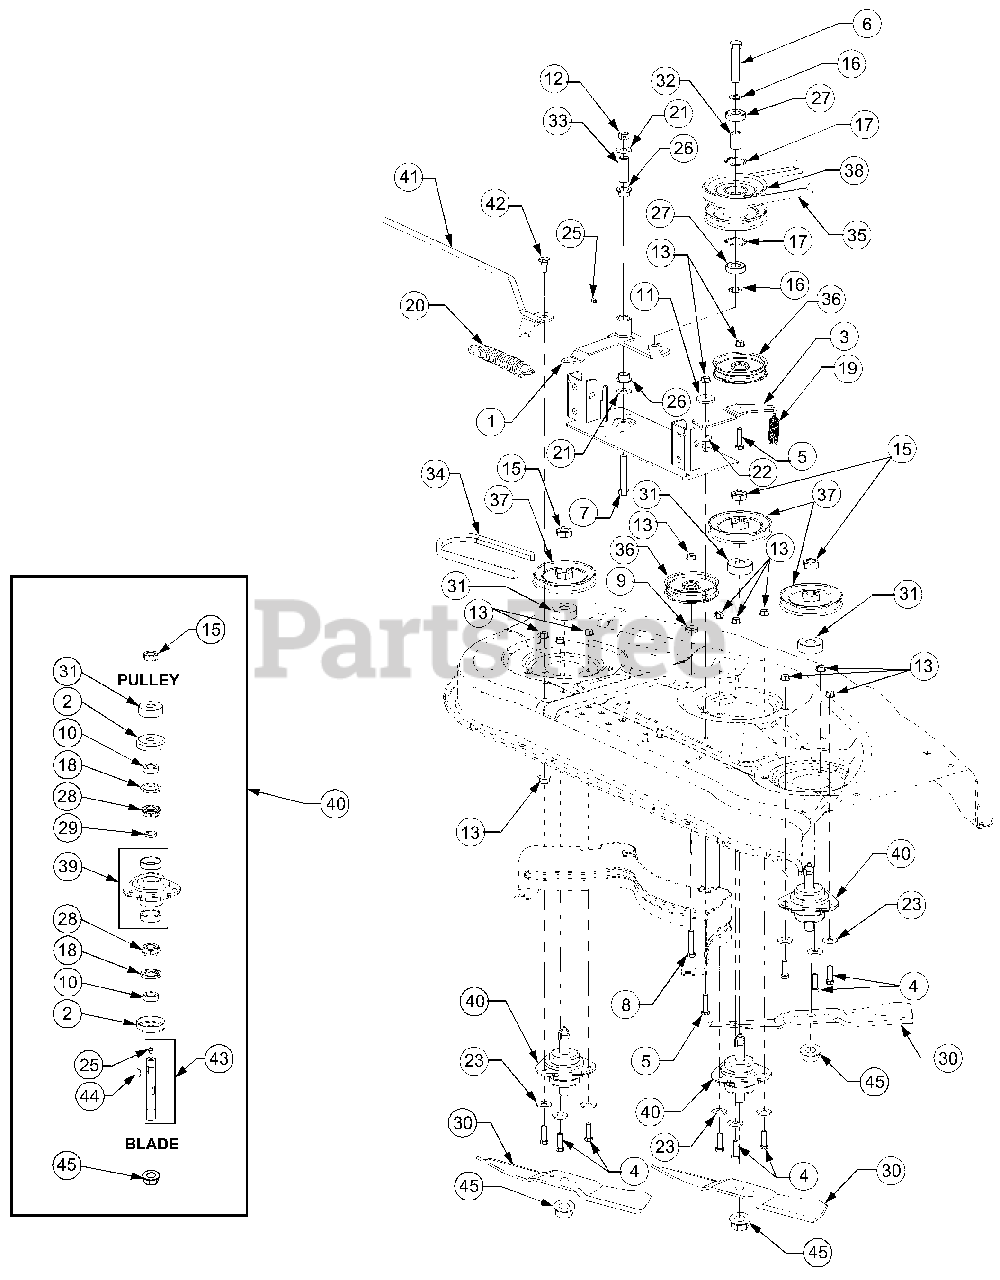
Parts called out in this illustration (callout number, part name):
1	Pivot Arm, Double Pulley
2	Cup, Spindle
4	Screw, Hex Cap 3/8-16 x 1.25 GR5
5	Screw, Hex Cap, 3/8-16 x 1.5 GR5
6	Screw, Hex Cap, 5/8-18 x 3 GR5
7	Screw, Hex Cap, 1/2-20 x 3 GR8
8	Screw, Hex Cap, 3/8-16 x 2
9	Spacer, .380 ID x 1 OD x .32
10	Spacer, .755 ID x 1.25 OD x .44
11	Spacer, Shoulder
12	Nut, Hex Center Lock, 1/2-20
13	Nut, Hex Flanged Lock, 3/8-16
15	Nut, Hex Jam, 3/4-16 GR5
16	Washer, Flat, .65 x 1.25 x .075
17	Snap Ring, Internal
18	Seal, Oil, 1.25 x 1.874 x .25
19	Spring, Extension, .75 OD x 6.12
20	Spring, Extension, 1.25 OD x 8.15
21	Washer, Flat, .531 x 1.25 x .1 Thk
22	Washer, Flat, .385 x 1 x .127 Thk
23	Washer, Flat, .406 x 1.0 x .105
25	Fitting, 3/16 Drive Lube
26	Bearing, Flange, 3/4 ID x .53
27	Bearing, Ball, .62 x 1.57 x .470
28	Cone, Bearing
29	Spacer, Bearing
30	Blade, Low Lift, 16.5"
31	Spacer
32	Spacer, Pulley, .635 ID x .88 OD x
33	Spacer, Idlr Brkt, .51 ID x .75 OD x
34	Belt, Spindle, A-Section x 105"
35	Belt, PTO, B-Section x 111.2"
36	Pulley, Flat Idler, 4.06 OD
37	V-Pulley, 4.70 OD
38	Pulley, Double
39	Housing w/Cups, Spindle
40	Spindle Ass'y, Blade
42	Bolt, Shoulder, .498 Dia. x .340
43	Kit, Shaft w/Seal
44	Key, #91 Woodruff, 1/4 x 3/4
45	Nut, Hex Flange, 3/4-16
